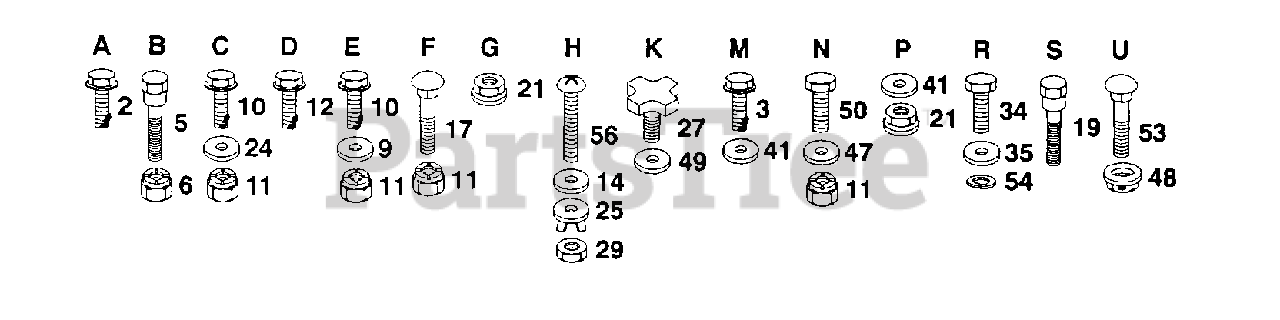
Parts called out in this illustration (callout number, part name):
2	SCREW
3	SCREW GTV
9	WASHER
12	SCREW LT
17	BOLT
19	"BOLT,SHOULDER"
21	PAL NUT LT
24	WASHER
25	RETAINER
27	"KNOB 1/2"" YT"
29	"GROMMET,PLASTIC"
35	WASHER PM
41	WASHER
47	WASHER
49	WASHER
50	BOLT
53	BOLT
54	LOCKWASHER
56	"SCREW,SPECIAL"
